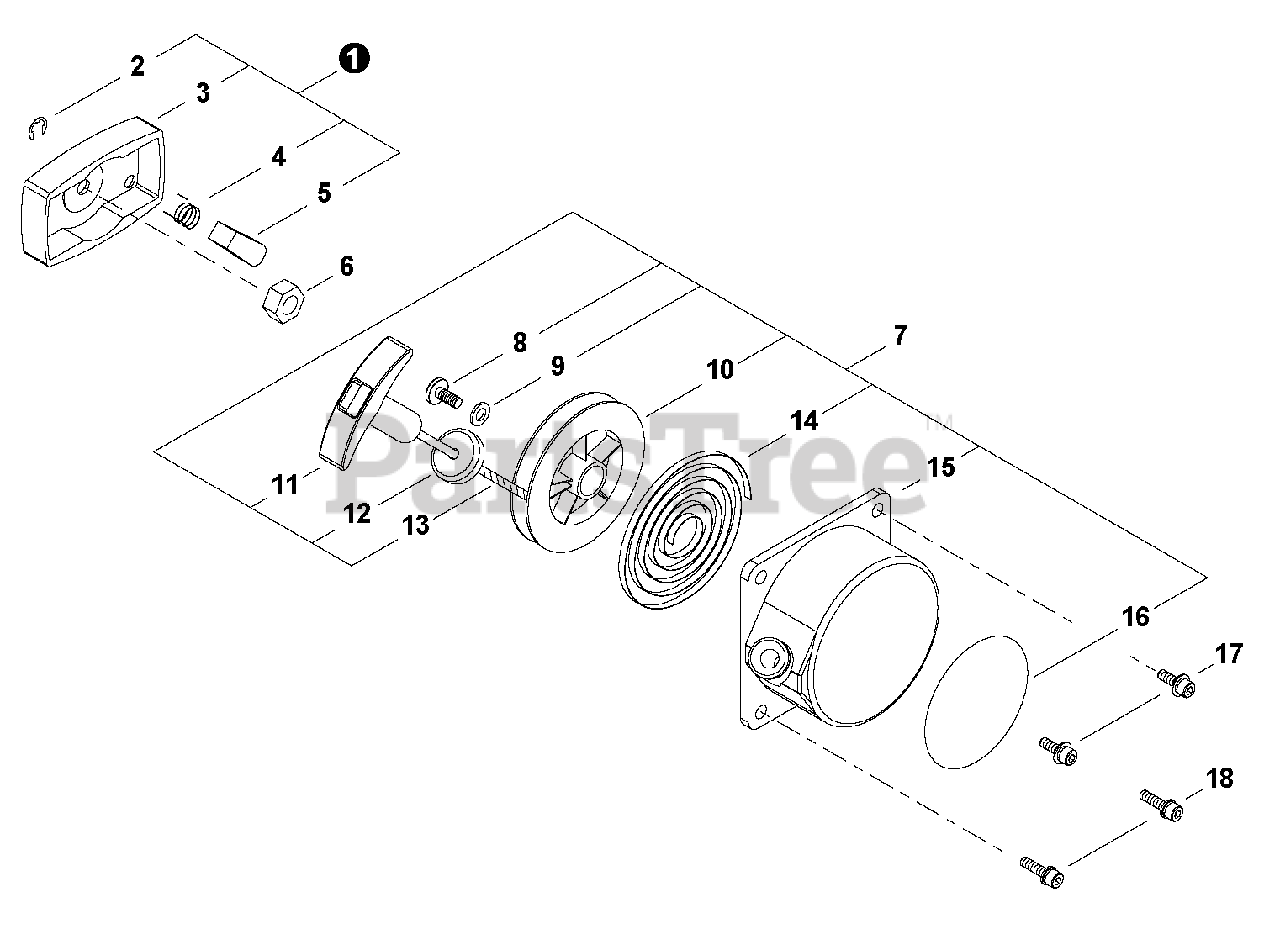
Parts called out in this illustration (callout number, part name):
1	PULLEY ASSY, STARTER
2	E-RING 4
3	PULLEY, STARTER
4	SPRING, RETURN
5	PAWL, STARTER
7	STARTER ASSY, RECOIL
8	SCREW 5
9	WASHER
10	REEL, ROPE
11	GRIP, STARTER
13	ROPE, STARTER
14	SPRING, RECOIL
15	CASE, STARTER
16	LABEL, TRADE
17	BOLT M5×16
18	BOLT M5×25
